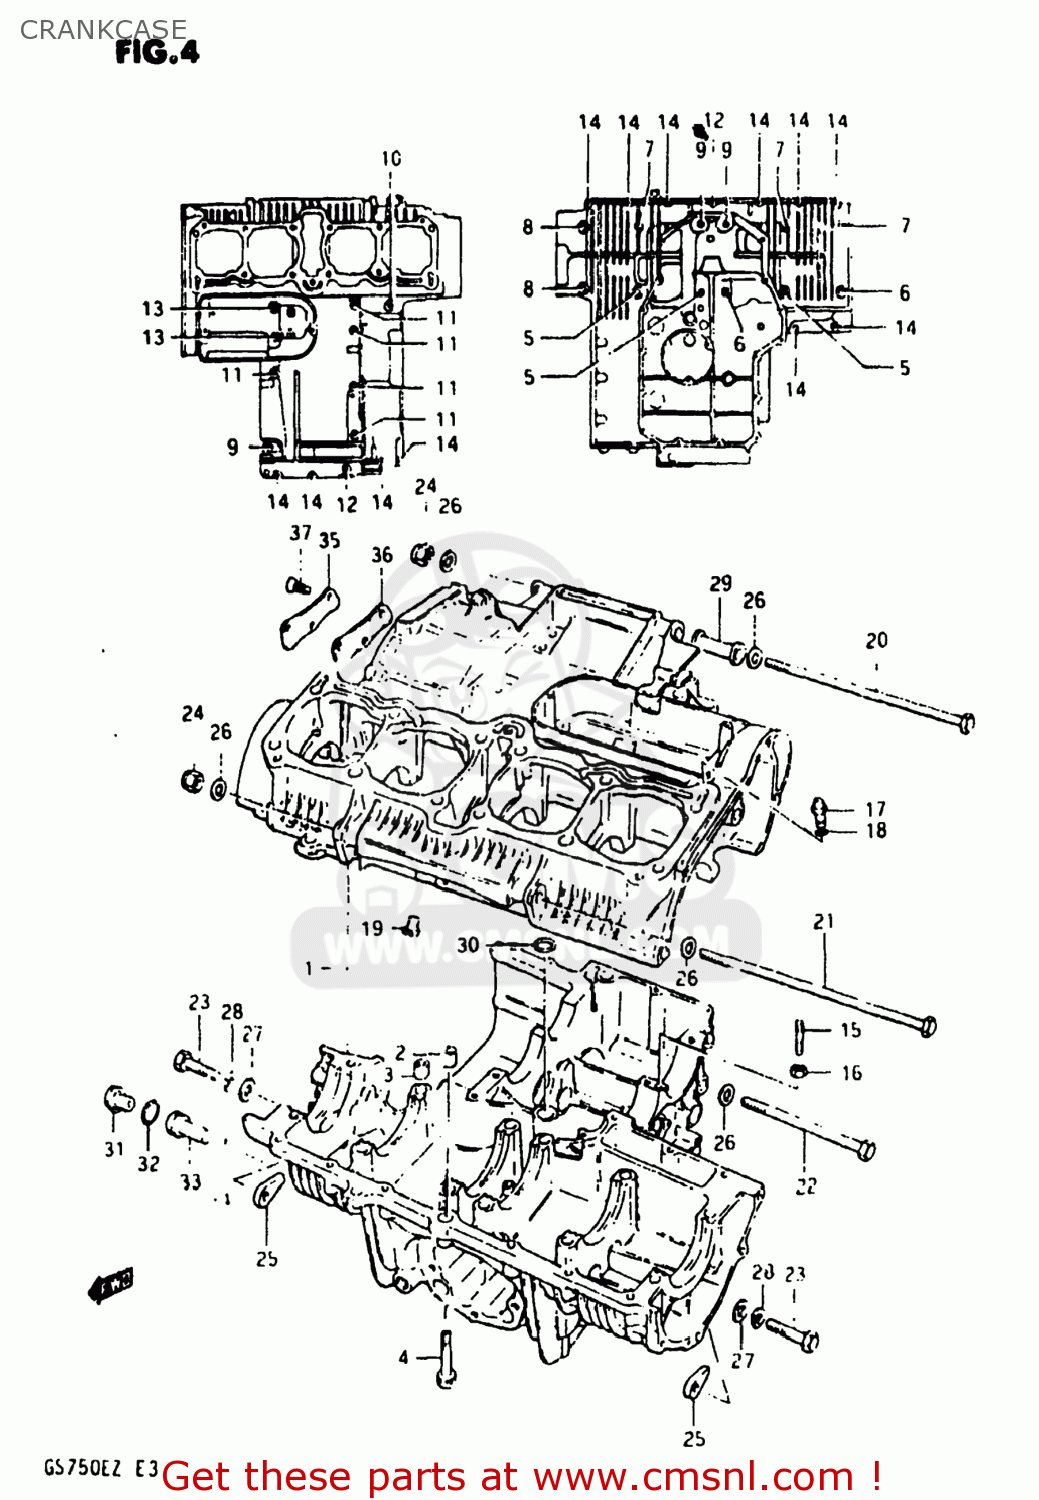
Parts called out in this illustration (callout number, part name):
1	CRANKCASE ASSEMBLY
2	PIN(10.4X13X22)
3	PIN (11X20)(SUS)
4	BOLT
5	BOLT(8X140)
6	BOLT
7	BOLT (8X95)
8	BOLT (8X70)
9	BOLT 8X65
10	BOLT 6X95
11	BOLT (6X80)
12	BOLT (6X60)
13	BOLT,UNDER
14	BOLT
15	STUD BOLT
16	NUT
17	JET
18	O RING(D:1.05,ID:3.1)
19	JET,AIR
20	BOLT 10X230
21	BOLT 10X250
22	BOLT(10X165)
23	BOLT 10X60
24	NUT
25	NUT
26	WASHER
27	WASHER(10.5X20X3.2)
28	LOCK WASHER
29	SPACER,ENGINE MOUNT
30	O RING(D:3.2,ID:12.9)
31	PLUG
32	O RING(D:2.4,ID:17.8)
33	PIN,OIL GALLERY
34	SEAL (D:1.9 ID:9.8)
35	CAP,OIL GALLERY
36	GASKET,OIL GALLERY (MCA)
37	SCREW
